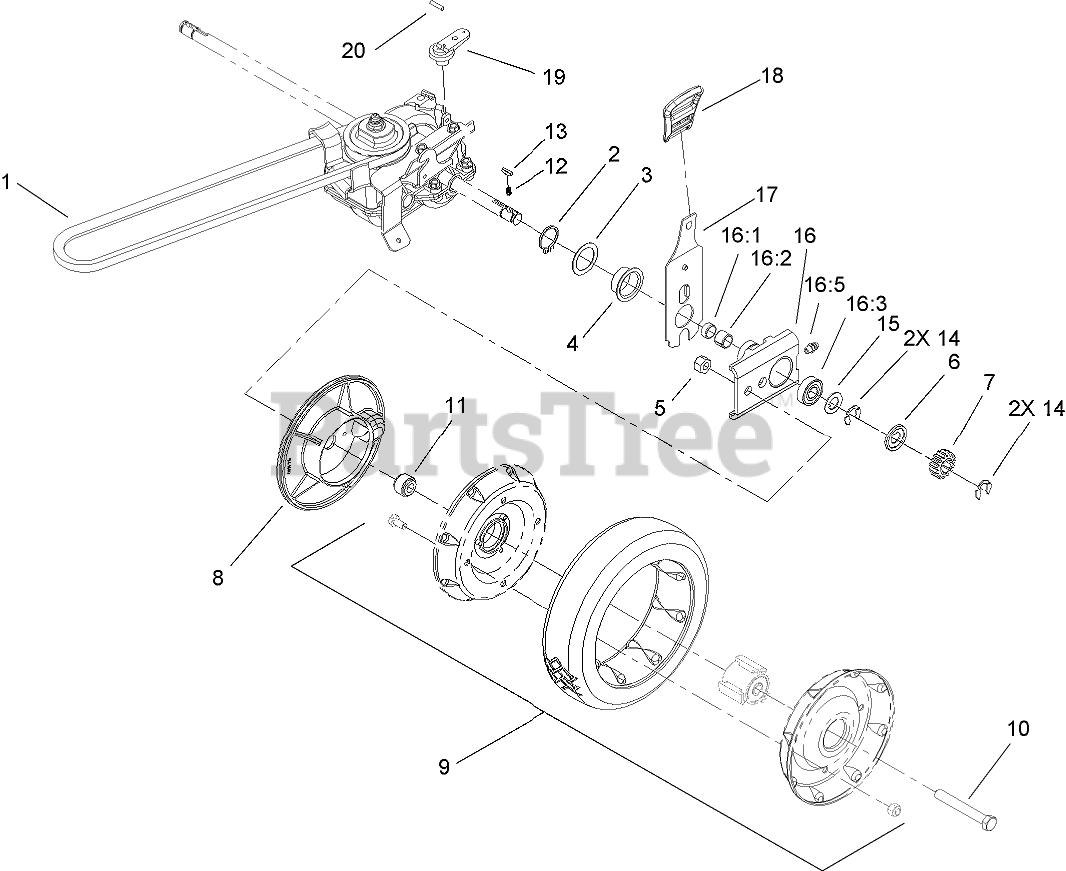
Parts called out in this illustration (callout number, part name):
1	V-BELT
2	RING-RETAINING
3	WASHER
4	CAP-END
5	NUT-LOCK, CONE
6	WASHER-THRUST, OUTER
7	GEAR-PINION
8	COVER-WHEEL
9	Wheel And Tire ASM
10	SCREW-HH
11	SPACER-COVER, WHEEL
12	SPRING-COMPRESSION
14	RING-RETAINING
15	WASHER-THRUST, OUTER
16	PIVOT ARM ASM
16:1	SEAL-OIL
16:2	BEARING-ROLLER
16:3	BEARING-WHEEL
17	REAR SPRING ARM ASM
18	KNOB-HOC
19	LEVER-SHIFT
20	PIN-COIL
